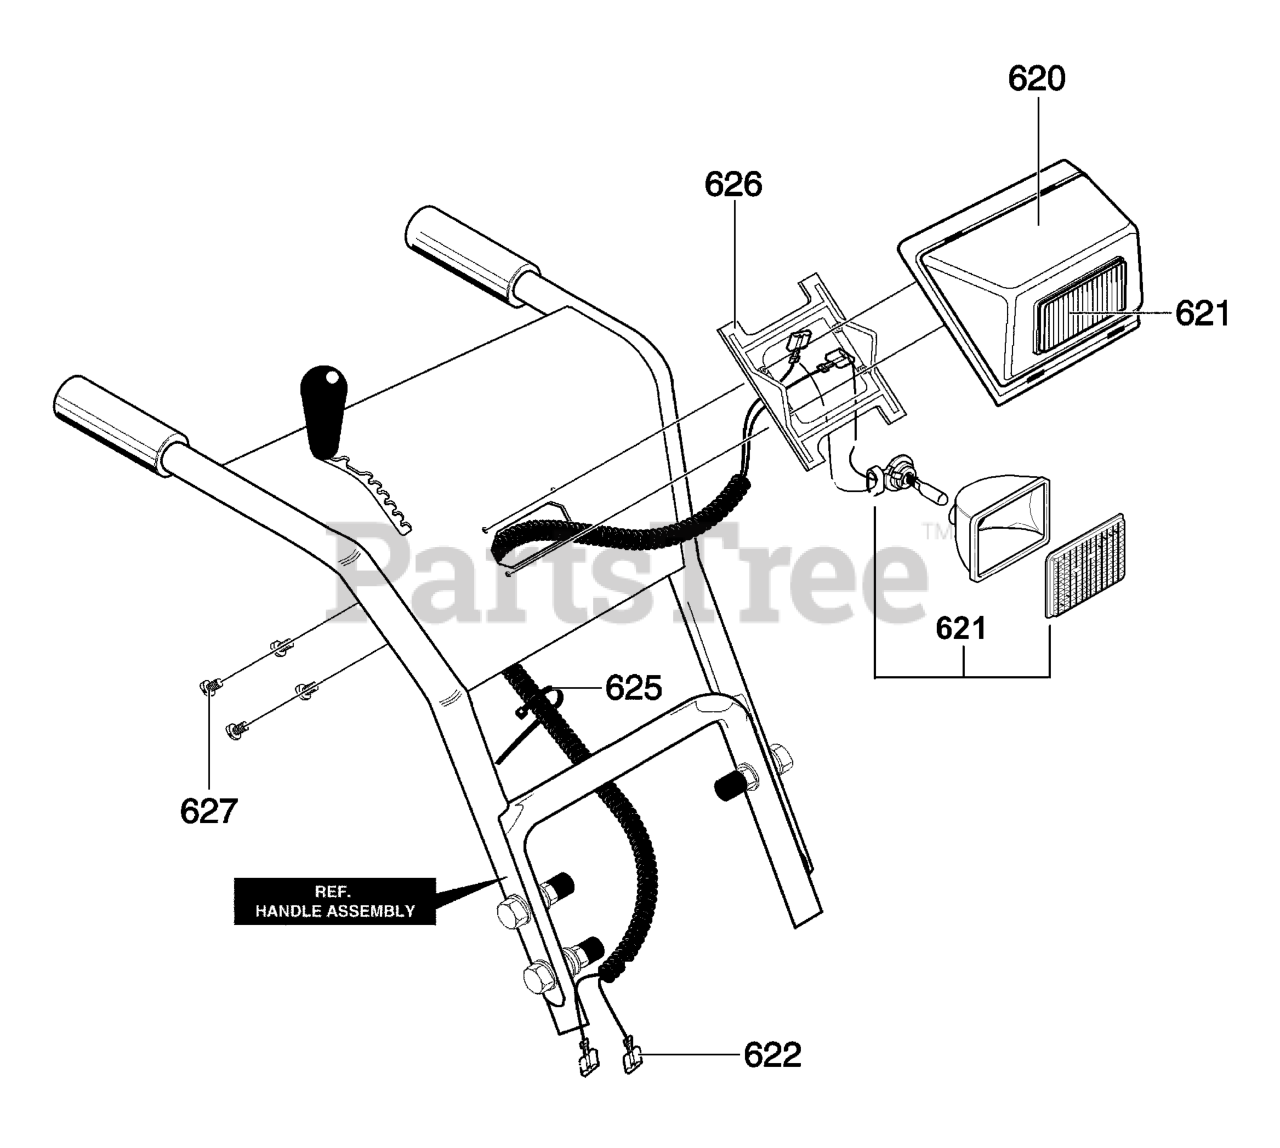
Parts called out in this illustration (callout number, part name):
620	HEADLAMP HOUSING
621	HEADLIGHT ASSY
622	WIRE, HARNESS
625	CABLE TIE
626	BRACKET, HEADLAMP
